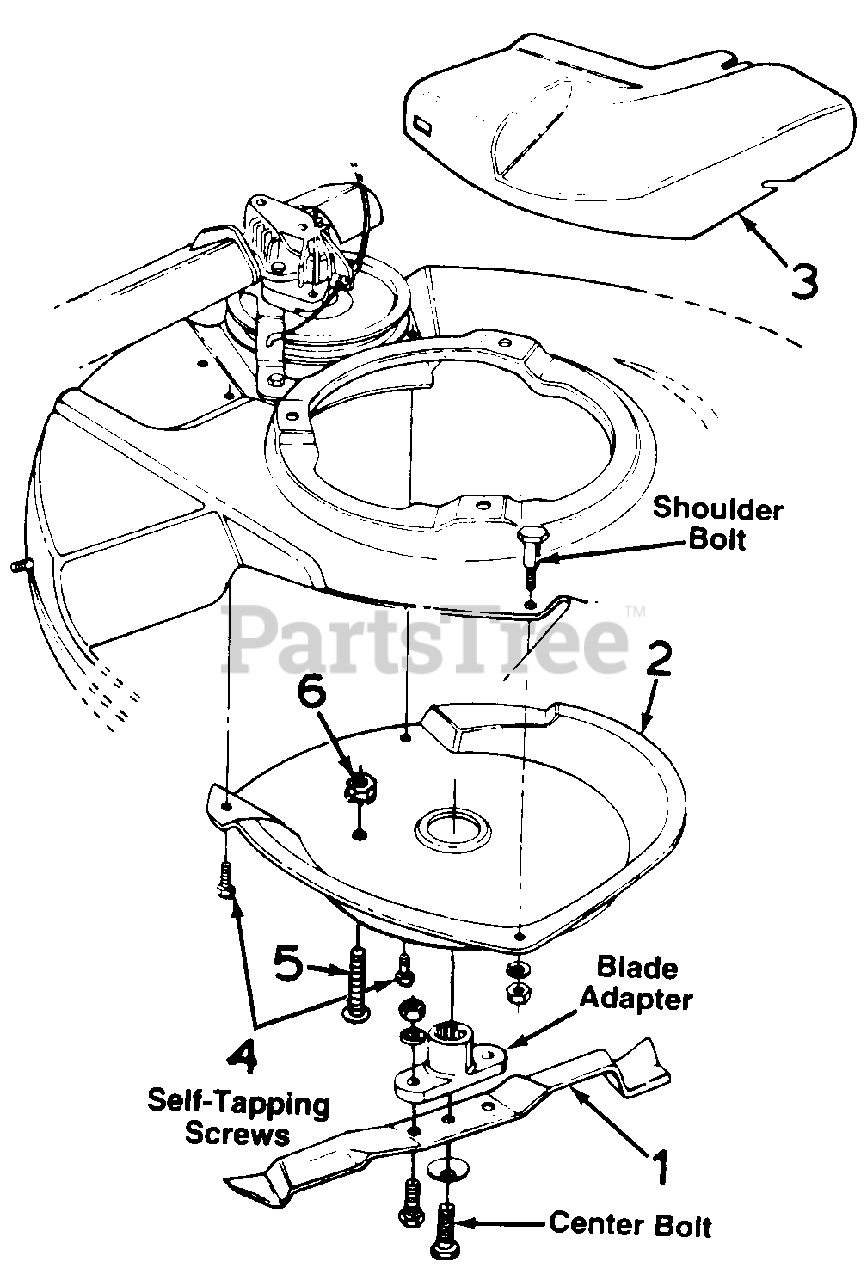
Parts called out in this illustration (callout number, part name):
1	Mulching Blade
2	Mulching Baffle
3	Mulching Plug
4	Self-Tapping Screw
5	Phillips Scr. 1/4-20 x 1.5"
6	Hex Sems Nut 1/4-20 Thd.
